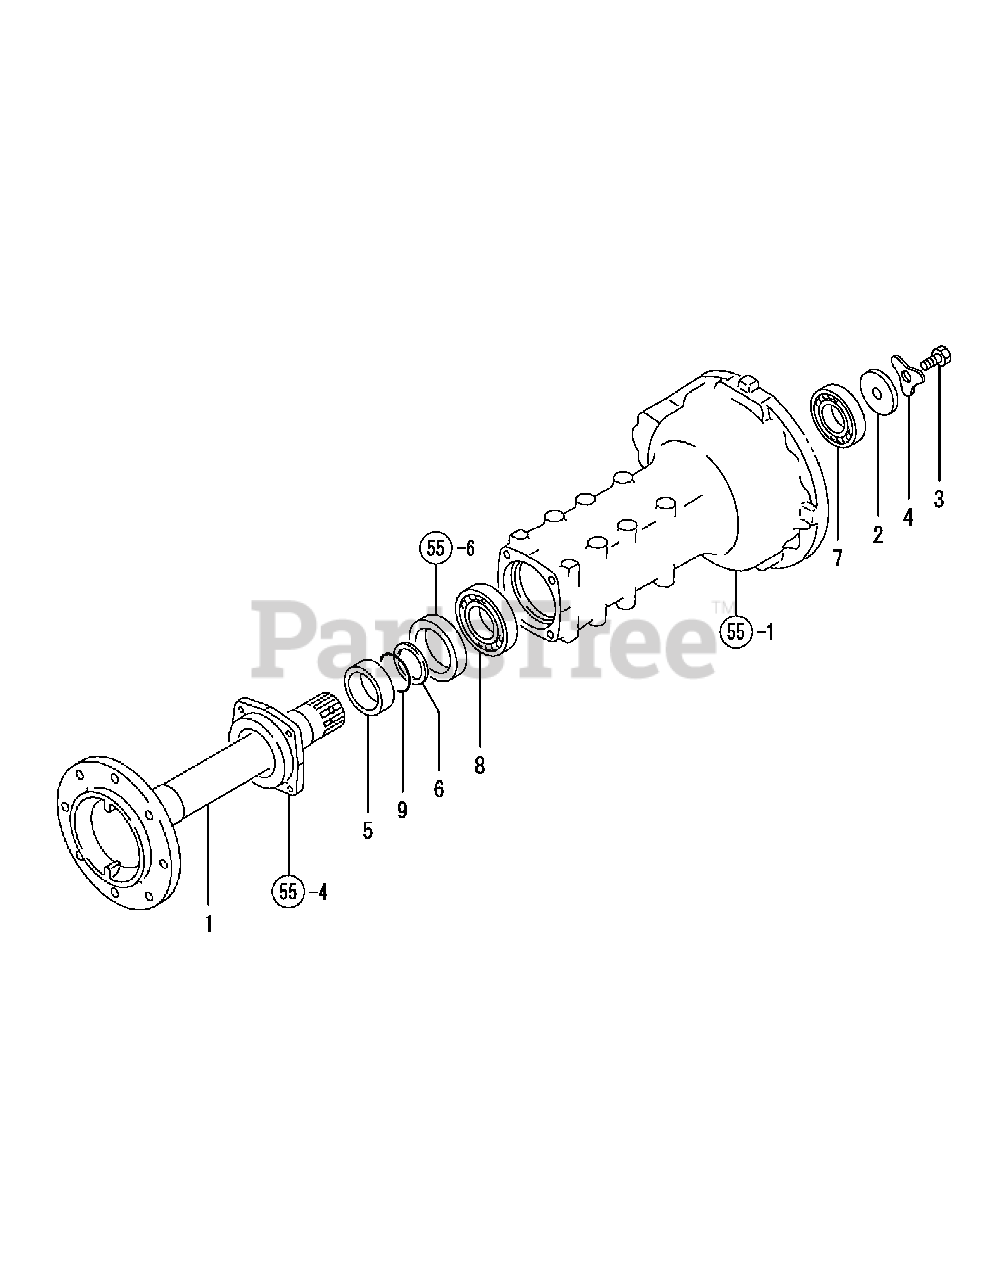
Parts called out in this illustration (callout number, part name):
1	SHAFT,REAR AXLE
2	WASHER 13X64X9
4	WASHER, THRUST
5	SEAL COLLAR 60X75X26
9	O-RING 1A G-60.0
